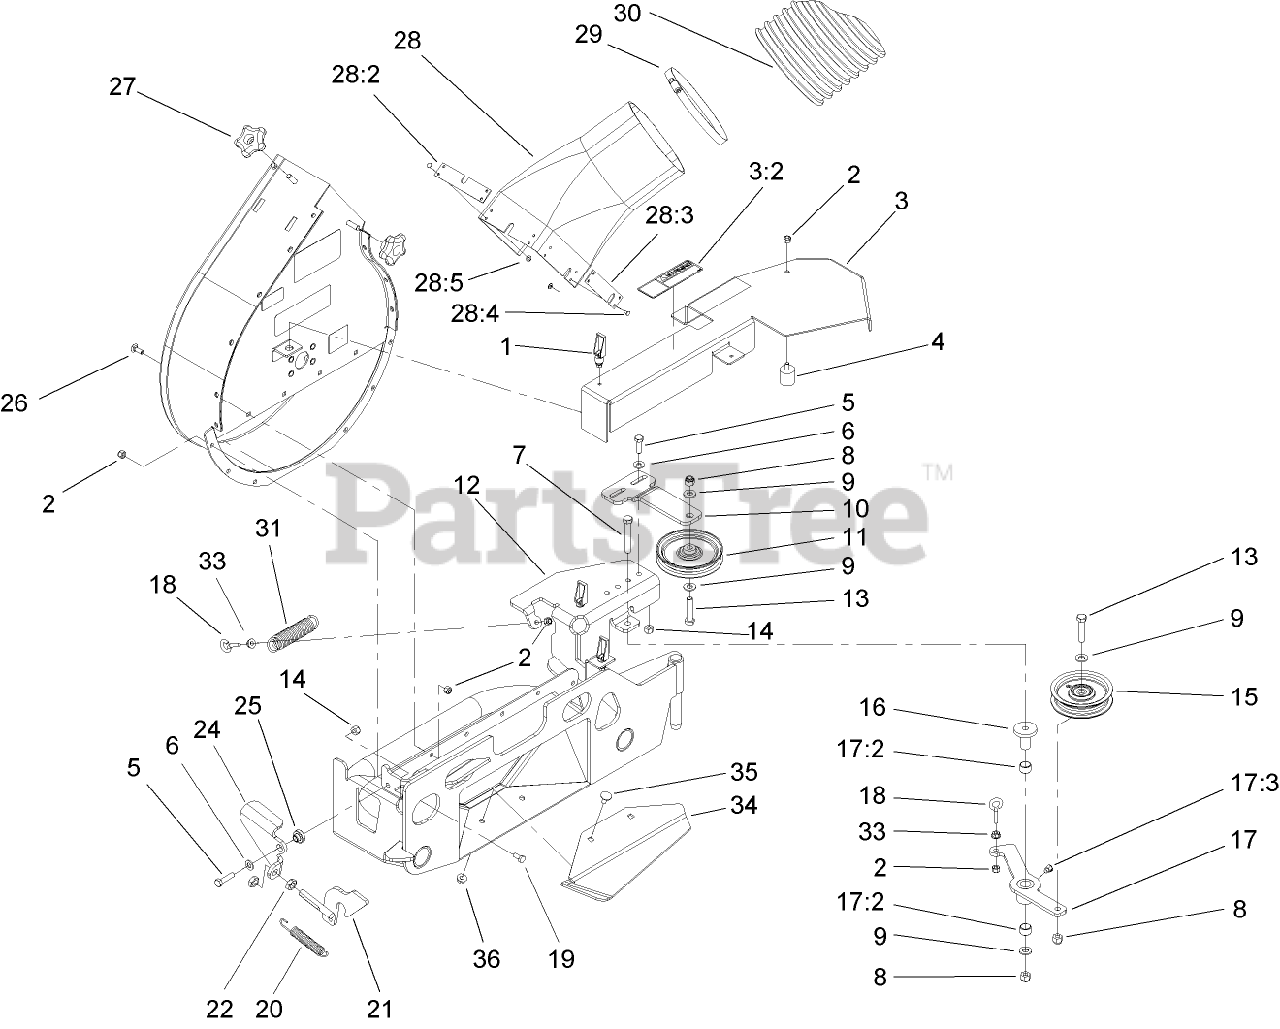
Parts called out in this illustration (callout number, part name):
1	LATCH-SWELL
2	NUT-LOCK, NI
3	BELT COVER ASM
3:2	DECAL-WARNING
4	Bumper
5	SCREW-HH
6	WASHER-PLAIN
7	SCREW-HH
8	NUT-LOCK, NI
9	WASHER-FLAT
10	Bracket-Idler
11	PULLEY-IDLER
12	TRANSITION ASM
13	SCREW-HH
14	NUT-LOCK, NI
15	PULLEY-IDLER, FLAT
16	Spacer
17	Idler Arm ASM
17:2	BUSHING
17:3	FITTING-LUBE, 45 DEG
18	BOLT-EYE
19	SCREW-HH
20	SPRING-TRACTION
21	LATCH ASM
22	NUT-JAM
24	PEDAL-LATCH
25	Spacer
26	BOLT-CARR
27	KNOB-HANDLE
28	Blower Outlet Adapter ASM
28:2	Plate-Adapter, Top
28:3	Plate-Adapter, Side
28:5	WASHER-FLAT
29	CLAMP
30	HOSE-FLEXIBLE
31	SPRING-EXTENSION
33	NUT-HF
34	SHELF-BLOWER
35	SCREW-CARR
36	NUT-HF
